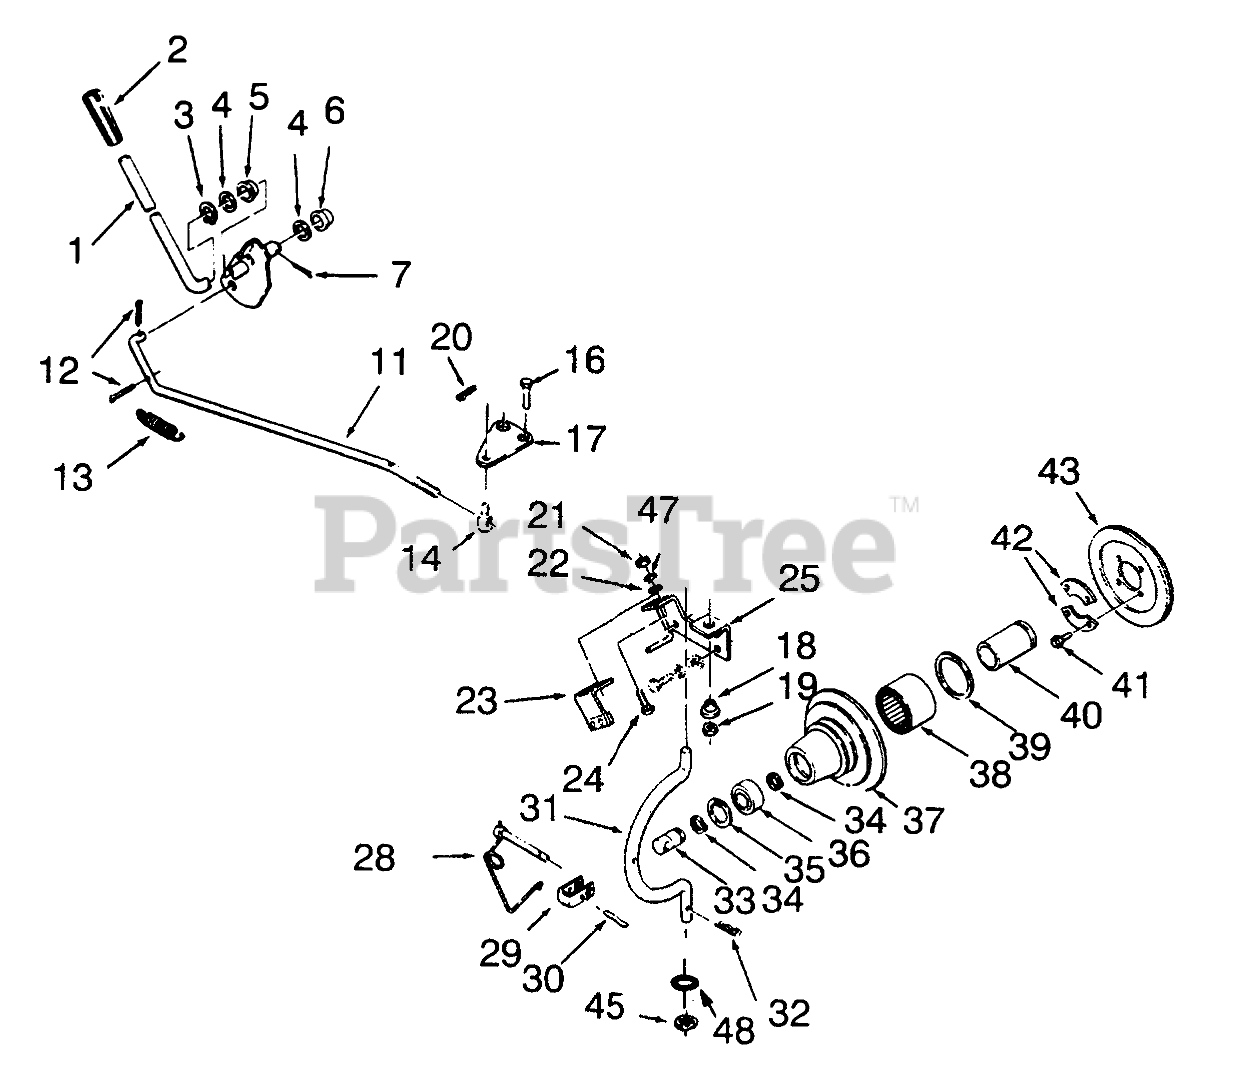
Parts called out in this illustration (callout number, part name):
1	ASSY PTO CLUTCH LEVE
2	GRIP
3	Grip Ring
4	SHIM-WASHER
5	BUSHING-NYLINER
6	NYLINER BUSHING
7	PIN-COTTER
11	ROD-PTO CLUTCH
12	PIN-COTTER
13	SPRING
14	TRUNNION
16	SCREW-HH
17	PLATE
18	SPACER-LIFT LINK
19	NUT-LOCK, NI
20	Hairpin Cotter
21	NUT-JAM
22	WASHER-FLAT
23	ASM-Bracket
24	SCREW-CARR
25	Bracket
28	LOCKING PIN ASM
29	CLEVIS
31	ROD-HOUSING
32	Hairpin
33	SHAFT-PTO
34	Ring-Snap
35	Ring-Snap
36	BEARING-BALL
37	Housing-Clutch
38	BRG-NEEDLE OPEN END
39	SEAL-OIL
40	RACE-BEARING
41	SCREW-HH
42	RETAINER
43	Facing-Clutch
45	RING-REINFORCED CIRC
47	WASHER-LOCK
48	WASHER-FLAT
